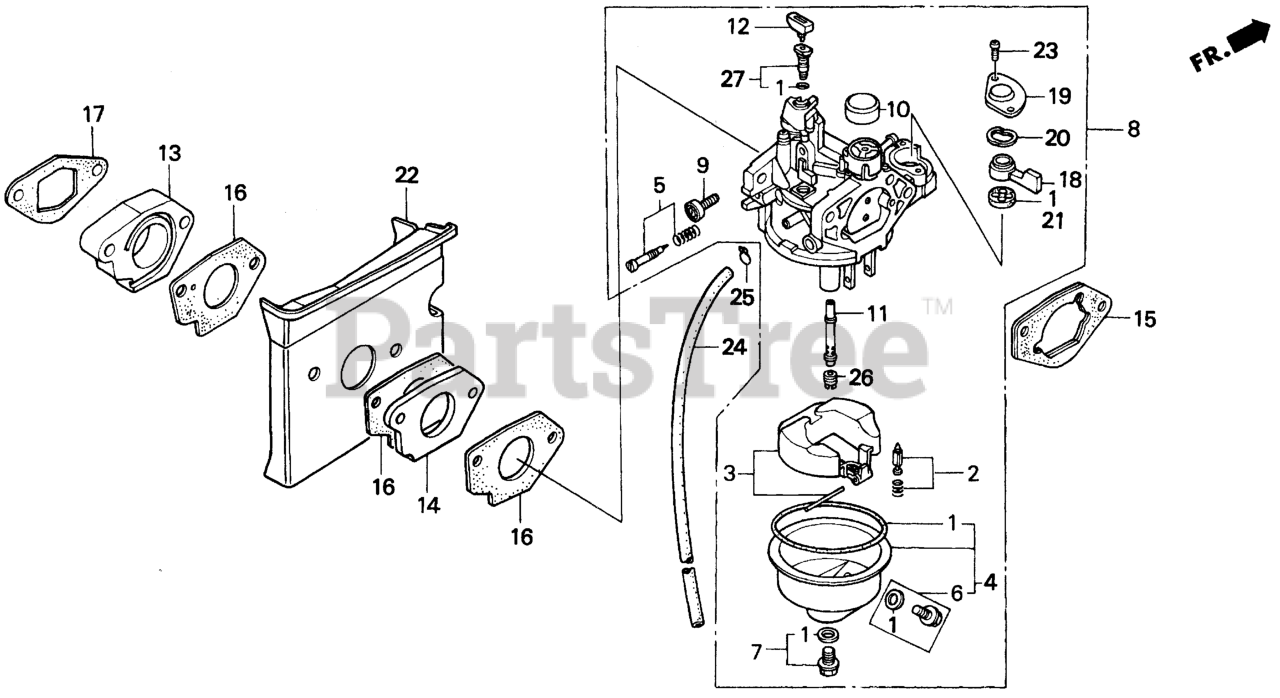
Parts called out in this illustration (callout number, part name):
1	GASKET SET (EXC. 16173-001-004) (CARBURETOR NO.) (EXCEPT 16173-001-004)
2	VALVE SET, FLOAT
3	FLOAT SET
4	CHAMBER SET, FLOAT
5	SCREW SET, PILOT (Honda Code 1441500). (CARBURETOR NO.)
6	SCREW SET, DRAIN (Honda Code 1672187). (CARBURETOR NO.)
7	SCREW SET B
7	SCREW SET
8	CARBURETOR ASSY. (BB36A C)
9	SCREW, THROTTLE STOP
10	CAP, CHOKE LEVER DUST
11	NOZZLE, MAIN
13	INSULATOR, CARBURETOR
14	INSULATOR, CARBURETOR
15	SPACER, CARBURETOR
16	GASKET, CARBURETOR
17	GASKET, INSULATOR
18	LEVER, VALVE
19	PLATE, LEVER SETTING (CARBURETOR NO.)
20	SPRING, PETCOCK LEVER (CARBURETOR NO.)
21	GASKET, VALVE
22	GUIDE, AIR
22	SCREW, PAN (3X6)
23	SCREW, PAN (3X6)
24	BULK HOSE, FUEL (4.5X1000) (4.5X180)
25	CLIP, TUBE (B8)
26	JET, MAIN (#82)
26	JET, MAIN (#85)
26	JET, MAIN (#88) Use from Engine SN BE27A B to BE27A E.
27	JET SET, PILOT (#40)
